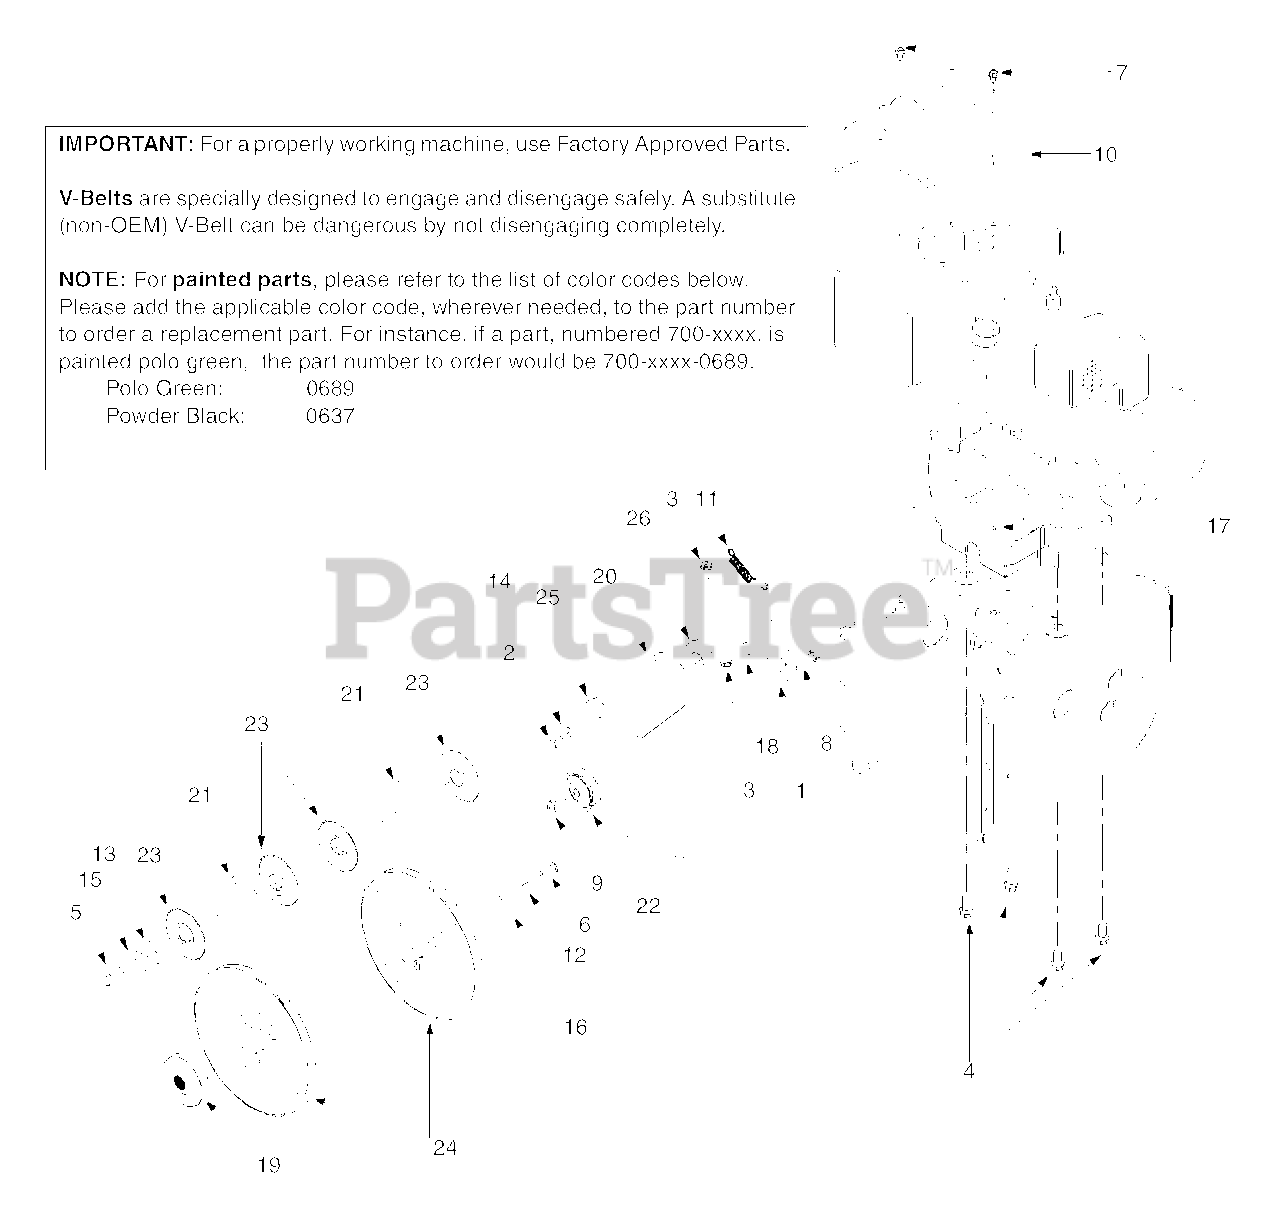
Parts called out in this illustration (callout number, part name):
3	Hex Screw w/ patch: 5/16-24 x 0.75"
4	Hex Washer Head TT Sems Screw
5	Hex Bolt 3/8-24 x .875" Gr.8
6	Hex Screw w/ Patch: 5/16-24 x .875" Gr.5
7	Hex Washer Head TT
8	Hex Screw: 3/8-16 x 1.0"
9	Top Lock Jam Nut: 3/8-16
10	Belt Cover
11	Extension Spring
12	Bellevile Washer
13	Flat Washer
14	Bell Washer
15	Bell Washer
16	Flat Washer
17	Grease
18	Shoulder Spacer
19	Adapter Pulley
20	V-Belt
21	Belt
22	Flat Idler
23	Pulley Half
24	Auger Pulley
25	Pulley Half
26	Pulley Half
